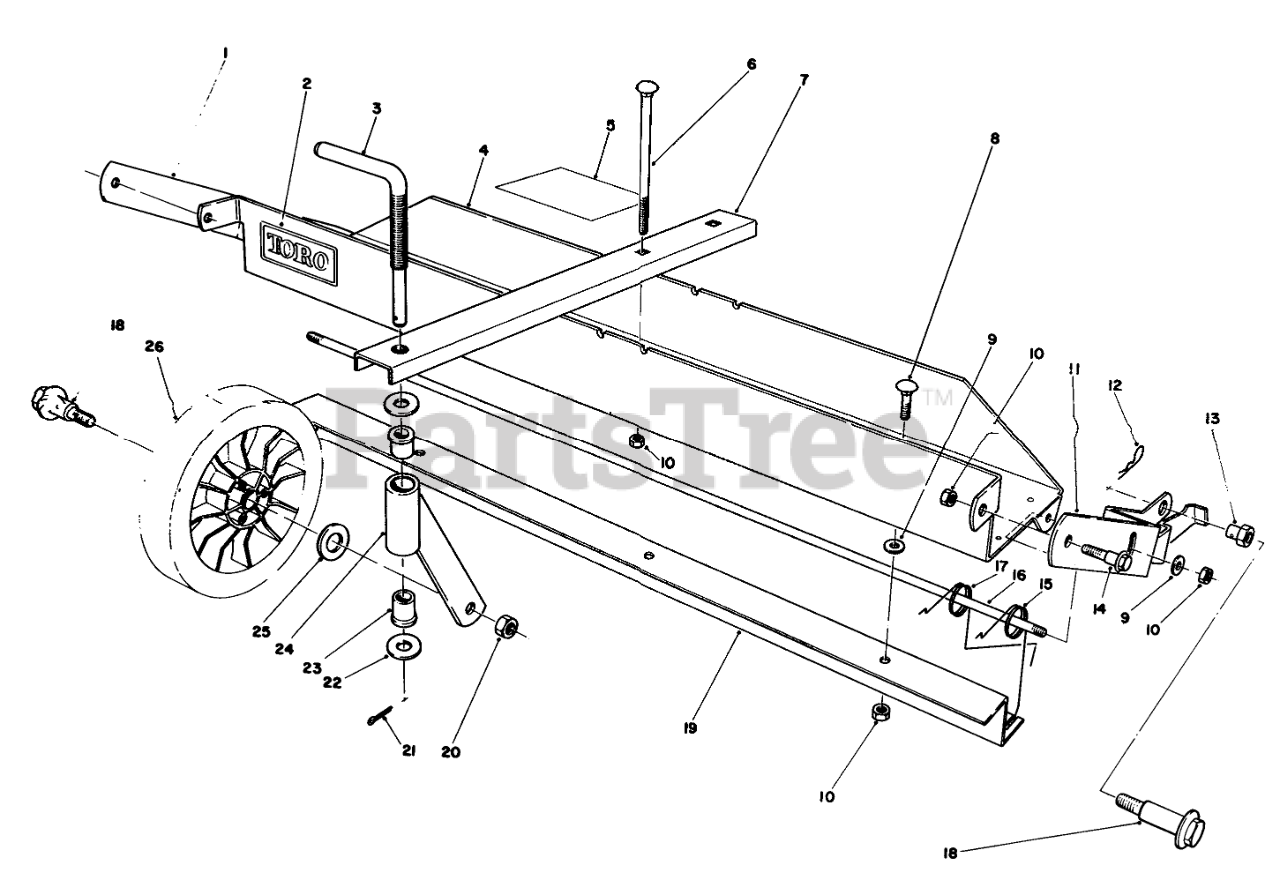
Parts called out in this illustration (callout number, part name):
1	Frame R.H.
2	Decal-Toro
3	CASTOR ADJ ROD
4	Frame-Main (Incl. Ref. #2)
5	Decal-Instruction
6	SCREW-CARR
7	Castor Frame
8	BOLT-CARR
9	WASHER-FLAT
10	NUT-HEX, SIDE DEFORM
11	LH MTG FRAME
12	PIN-COTTER, HAIR
13	PIVOT NUT
14	SCREW-SHOULDER
15	DETHATCHER SPRING
16	SPRING SUPPORT ROD
17	DETHATCHER SPRING
18	BOLT-WHEEL
19	SPRING GUIDE STRAP
20	NUT-LOCK
21	PIN-COTTER
22	WASHER-FLAT
23	FLANGE BUSHING
24	Castor Tube & Support
25	WASHER
26	Wheel Assembly
